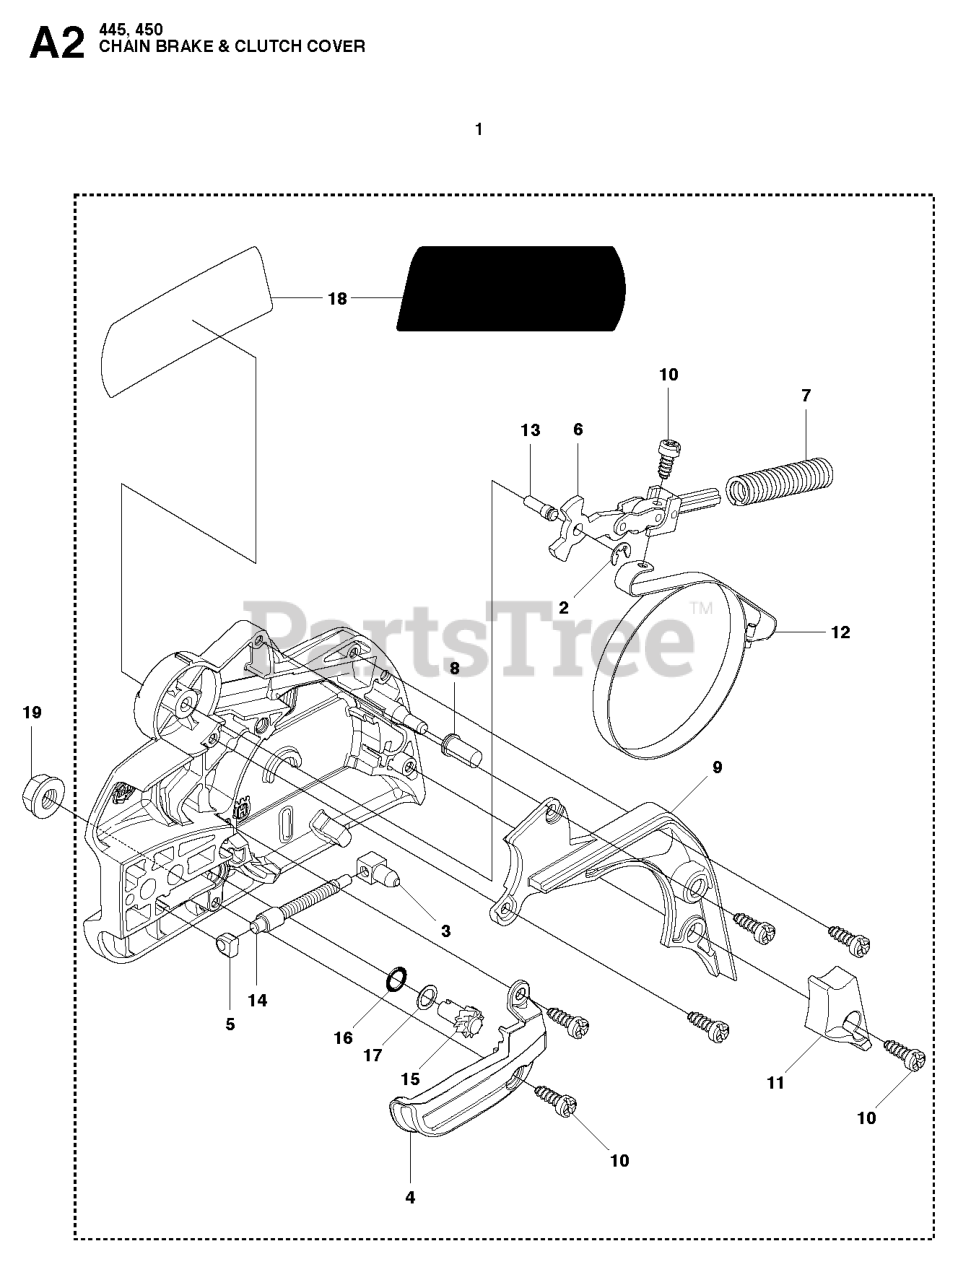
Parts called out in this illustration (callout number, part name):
1	CLUTCH COVER
4	CHAIN GUIDE
9	COVER, CHAIN BRAKE
11	WEAR GUARD, CHAIN
12	BRAKE BAND
15	WORM WHEEL
18	LABEL 400 SERIES
19	NUT M8 FLANGE
